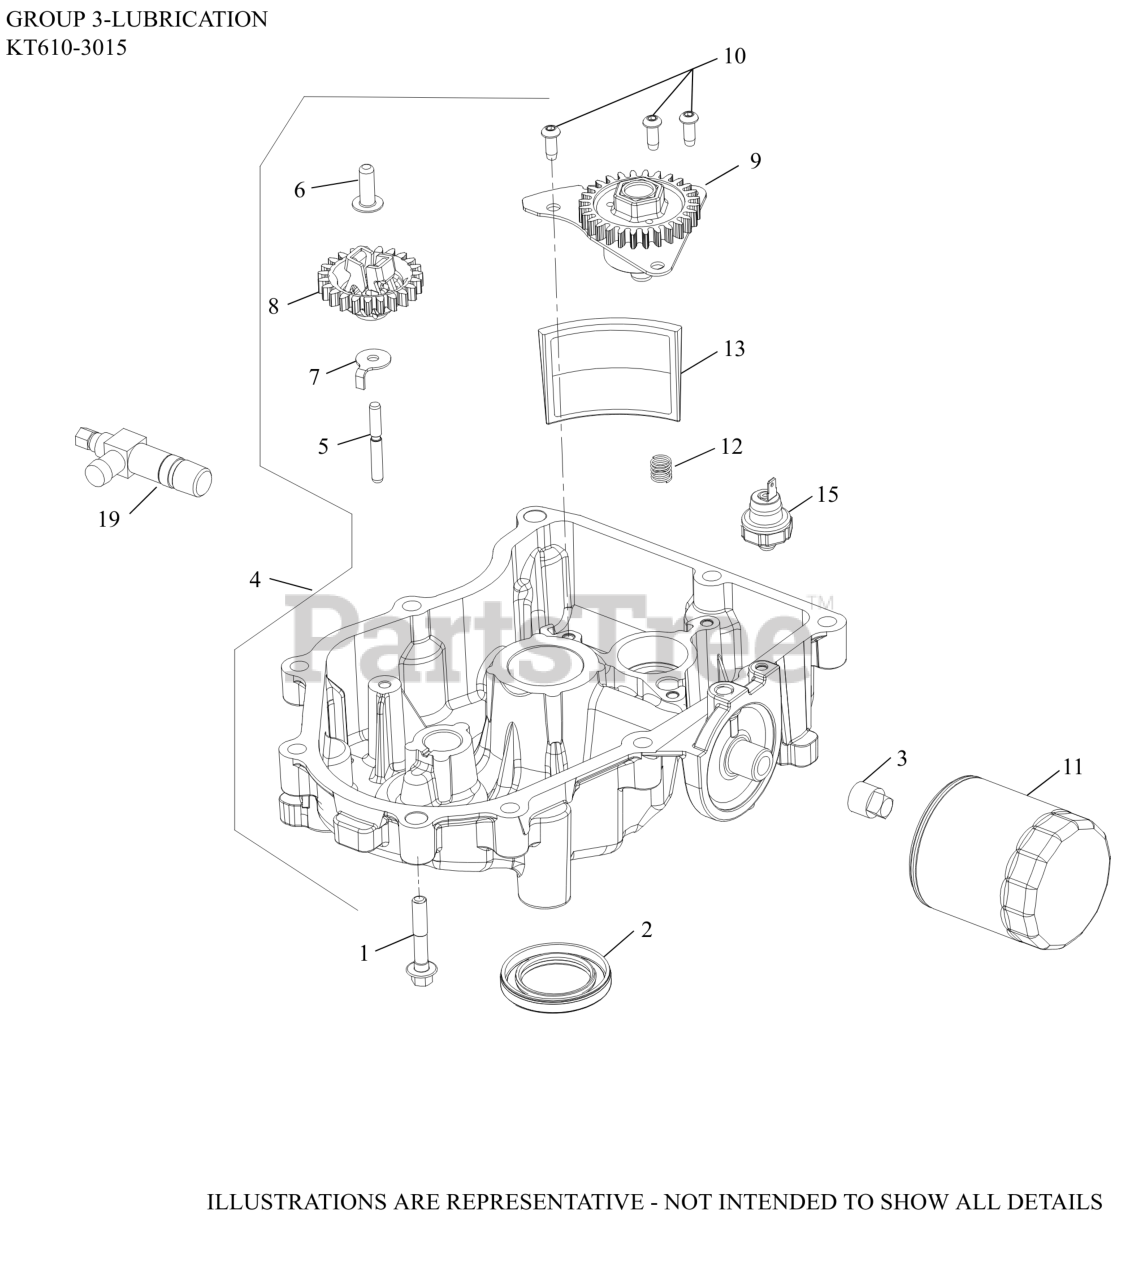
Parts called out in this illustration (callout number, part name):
1	SCREW, FLG M8X1.25X45
3	PLUG, SQ HD PIPE 3/8"
4	PAN ASSEMBLY, OIL-(#3219924S)
5	SHAFT, GOVERNOR GEAR
6	PIN, GOVERNOR REGULATING
7	TAB, LOCKING
8	KIT, GOVERNOR GEAR
9	PUMP ASSEMBLY, OIL
10	SCREW, BUTTON HEAD
11	OIL FILTER
12	SPRING, COMPRESSION
13	SCREEN, OIL
15	SENSOR, OIL PSI 3 TERMINAL
19	VALVE, OIL DRAIN MEDIUM
